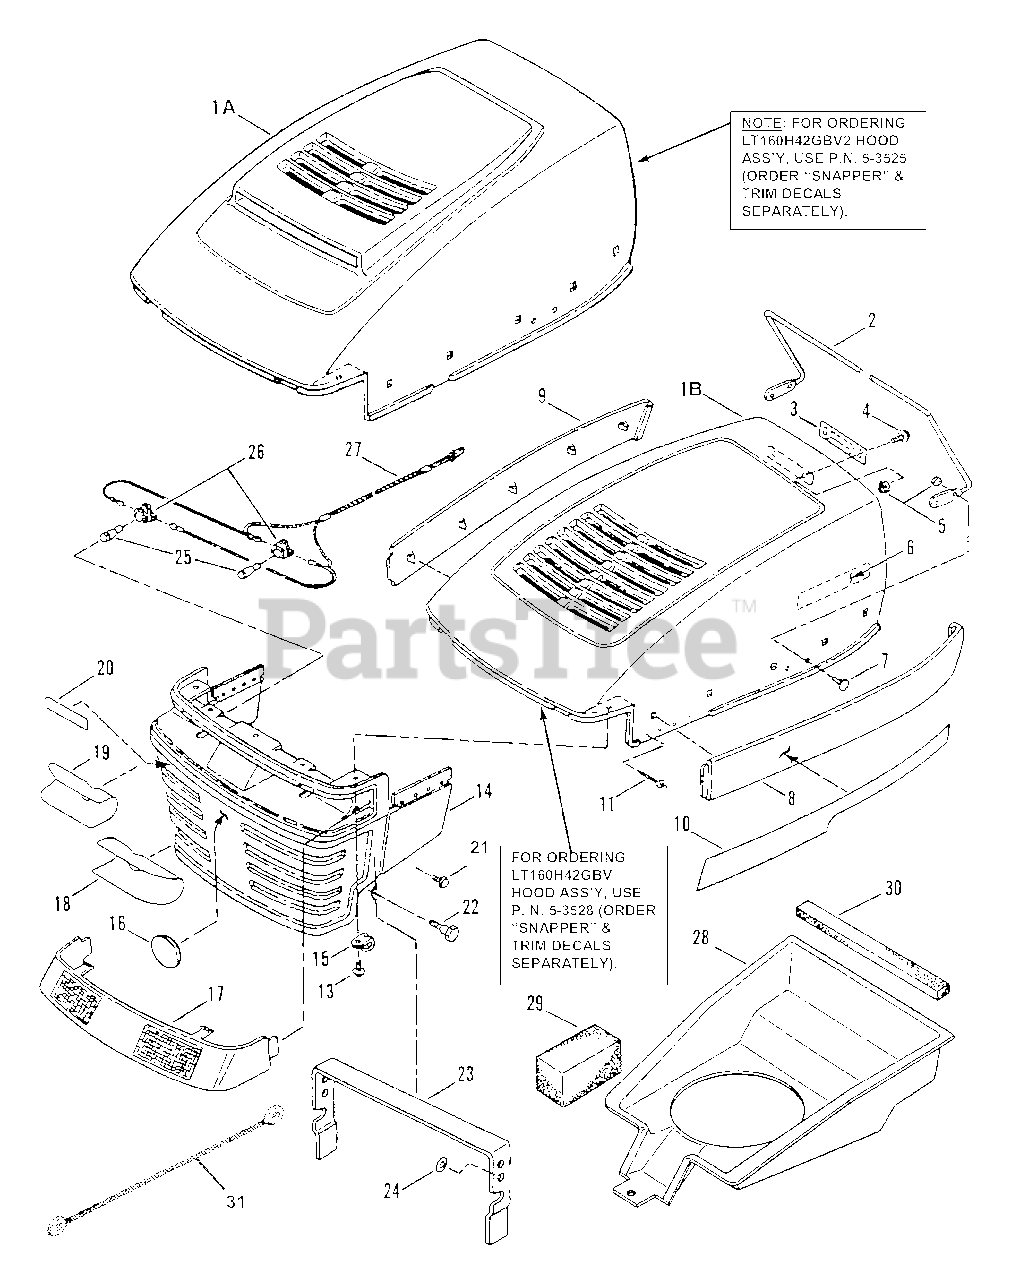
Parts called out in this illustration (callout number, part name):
1A	HOOD, Mozart (with Scoop) (Models: LT160H42GBV2 & LT180H48GBV2)
1B	HOOD, Mozart (Model: LT160H42GBV)
2	ROD, Hood Support
3	LATCH, Spring
4	SCREW, 1/4-20 x 5/8" Truss Head, Torx
5	NUT, 1/4-20 Hex Nyloc
6	DECAL, SNAPPER, 8" Molded Logo
7	BOLT, 1/4-20 x 5/8" Flat Head Carriage
8	PANEL, Hood (Left Hand)
9	PANEL, Hood (Right Hand)
10	DECAL, Hood (Right Hand) (Model: LT160H42GBV)
10	DECAL, Hood (Left Hand) (Model: LT160H42GBV)
10	DECAL, Hood (Right Hand) (Model: LT160H42GBV2)
10	DECAL, Hood (Left Hand) (Model: LT160H42GBV2)
10	DECAL, Hood (Right Hand) (Model: LT180H48GBV2)
10	DECAL, Hood (Left Hand) (Model: LT180H48GBV2)
11	RIVET, 1/8" Pop
13	SCREW, M4.8 x 1.59 x 16.00mm, Special
14	GRILLE, Hood
15	CLIP, "J"
16	DECAL, Molded Medallion
17	LENS, Grille (Headlights)
18	DECAL, Reflect (Left Hand)
19	DECAL, Reflect (Right Hand)
20	DECAL, SNAPPER, 4" Molded Logo (Silver Letters - Blue Stripe)
21	SCREW, 5/16-18 x 1/2" Self-Tapping
22	BOLT, Shoulder, 3/8-16 x 1-1/4" Hex Socket, Torx
23	BRACE, Hood Support
24	RETAINER, 5/16" Bolt
25	BULB, Headlights
26	SOCKET, Headlight Bulb
27	HARNESS, Headlight Wiring
28	PLENUM (Models: LT160H42GBV2 & LT180H48GBV2 Only!)
29	FOAM, 2 x 2 x 3.5" (Models: LT160H42GBV2 & LT180H48GBV2 Only!)
30	FOAM, 1/2 x 3/4 x 14.25" (Models: LT160H42GBV2 & LT180H48GBV2 Only!)
31	LANYARD, Hood (Model LT160H42GBV)
31	LANYARD, Hood (Models LT160H42GBV2 & LT180H48GBV2)
